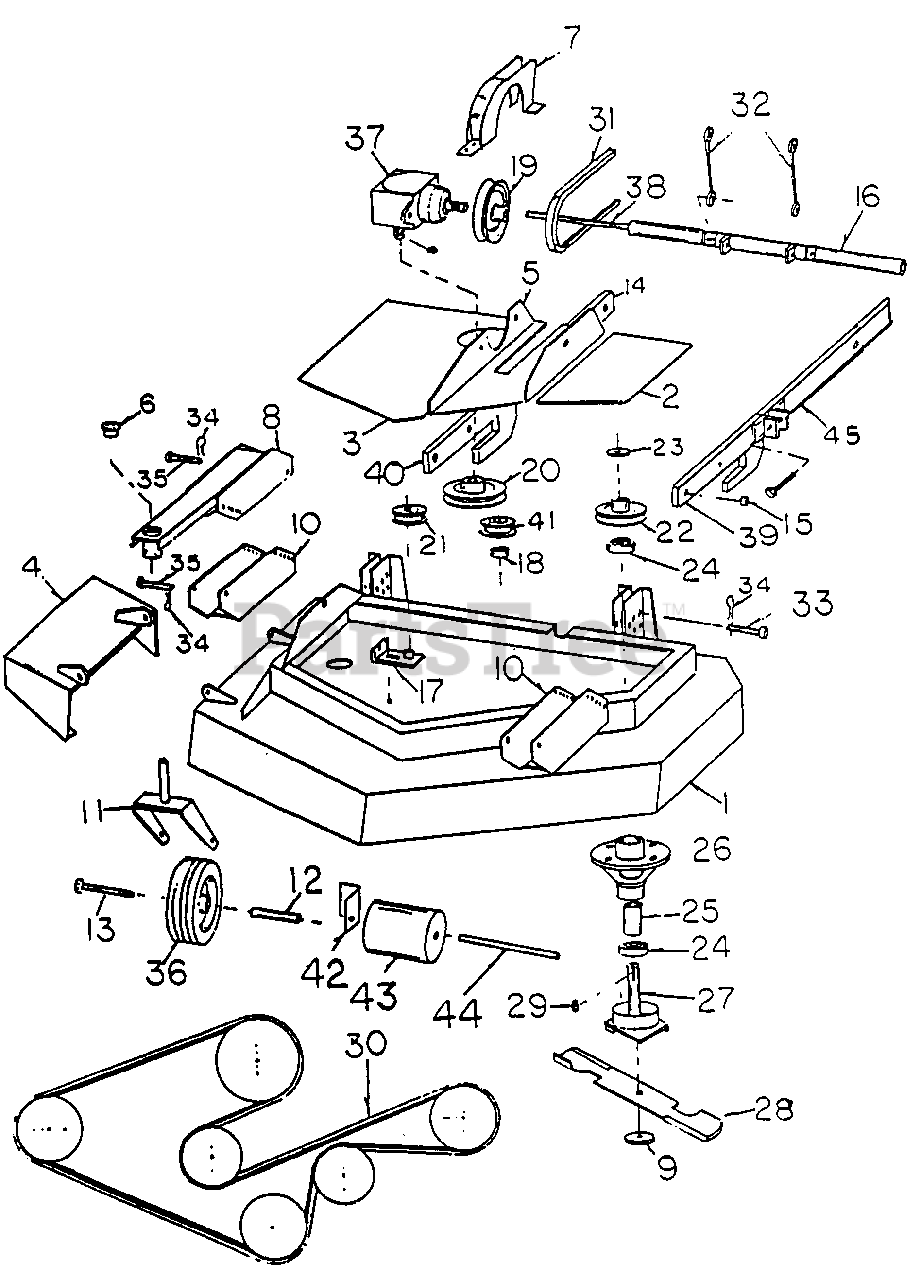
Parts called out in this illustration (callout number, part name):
3	COVER (LARGE)
4	FOOT GUARD
5	GEAR BOX MOUNT
6	GACE WHEEL BUSHING
7	BELT GUARD
8	GAGE WHEEL MOUNT
10	BRACKET GAGE WHEEL MOUNT
11	FORK, GAGE WHEEL
12	AXLE GAGE WHEEL
13	GAGE WHEEL BOLT
14	DECK LIFT ARM BACK ADJUSTABLE
15	BUSHING DECK LIFT ARM
18	SPACERf IDLER
19	PULLEY GEAR BOX
20	PULLEY GEAR BOX
21	PULLEY IDLER TIGHTENER
22	PULLEY SPINDLE
23	WASHER, SPINDLE
24	BEARING, SPINDLE
25	SPACER SPINDLE
26	HOUSING, SPINDLE
27	SHAFT, SPINDLE
29	KEY SPINDLE
35	PINS GAGE WHEEL
38	CROSS BAR PIN
39	L.H. DECK LIFT ARM FRONT ADJUSTABLE
40	R.H. DECK LIFT ARM FRONT ADJUSTABLE
42	ROLLAR BRACKET
45	L.H. DECK LIFT ARM BACK ADJUSTABLE
